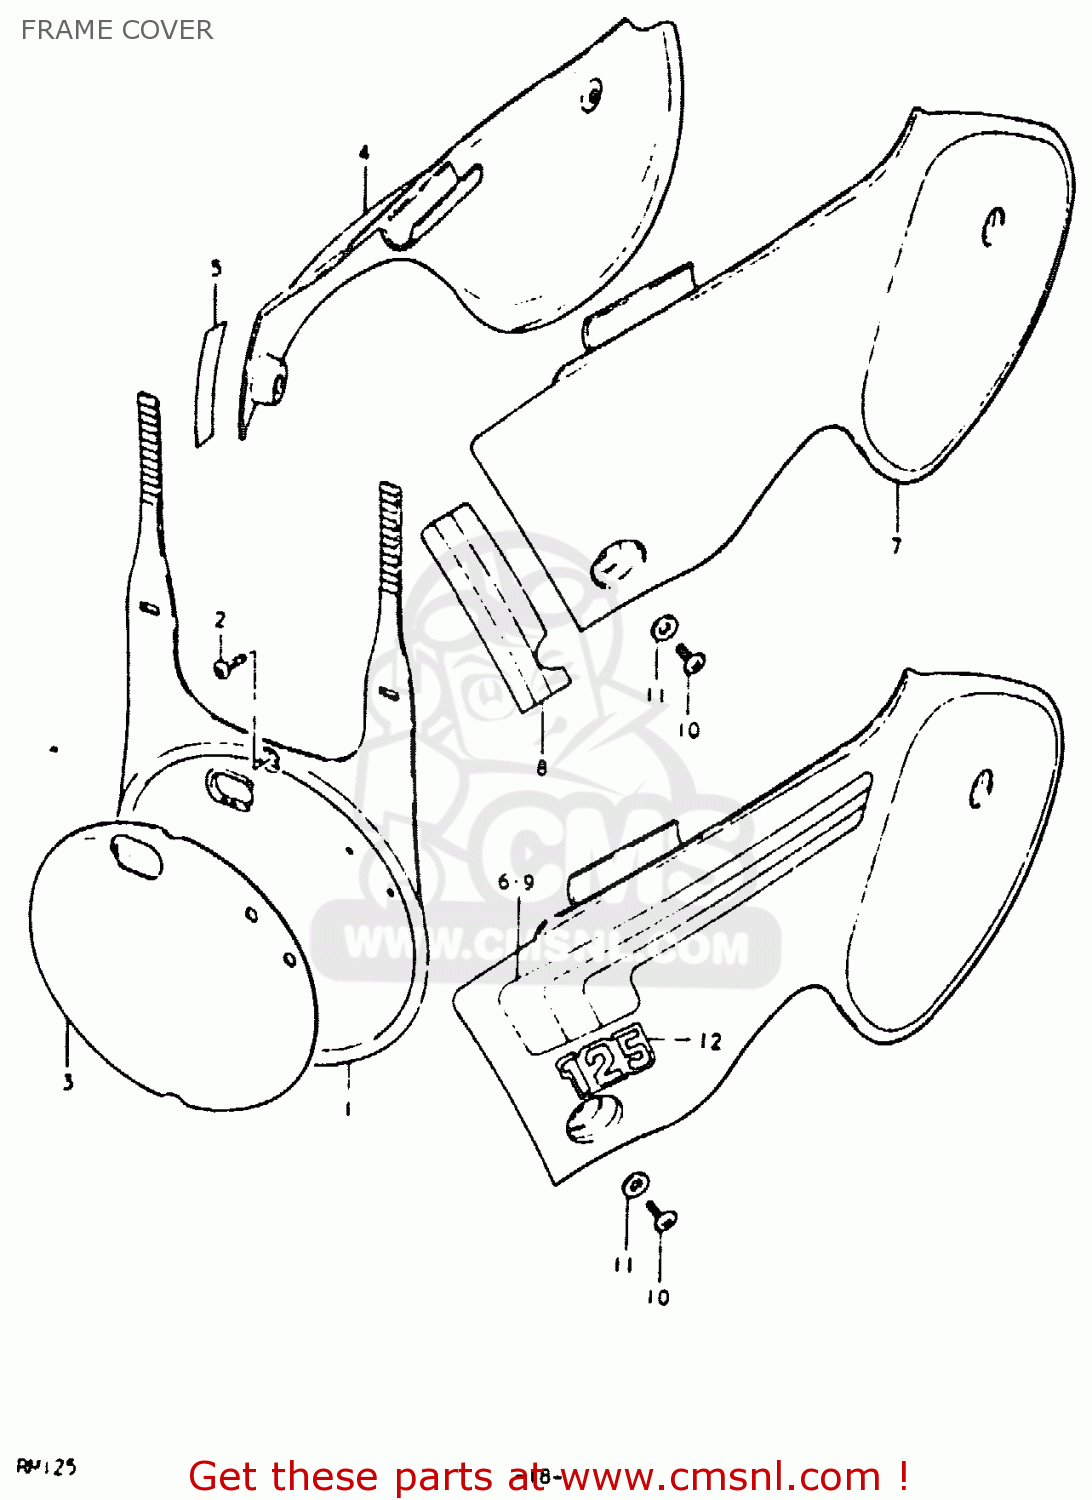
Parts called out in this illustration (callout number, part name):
1	PLATE,FR NUMBER
2	(5X20) CROSS SCREW
3	EMBLEM,FRONT NUMBER PLATE
4	COVER,FRAME,RIGHT
5	TAPE, RH
7	COVER,FRAME,L(YELLOW)
8	TAPE,FRAME COVER,LEFT STRIPE
10	SCREW 6X12
11	WASHER
